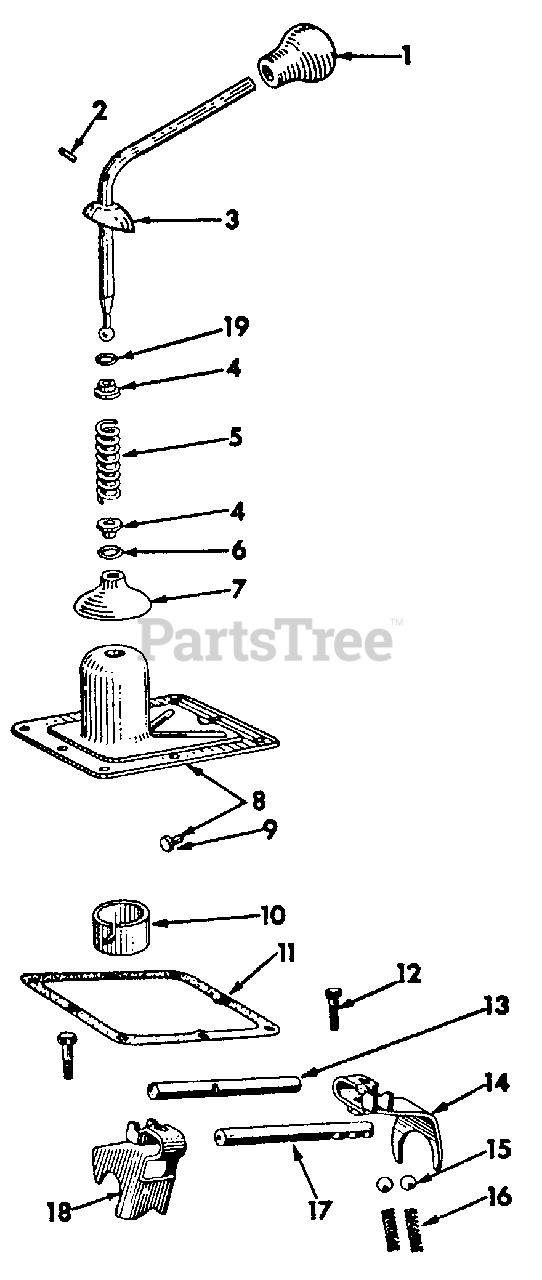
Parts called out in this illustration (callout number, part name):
1	Knob, Shift Handle
2	Pin, Gear Shift Swivel Spring Retainer
3	Lever Assy, Gear Shift
4	Retainer, Gear Shift Swivel Spring
5	Spring, Gear Shift Lever
6	O-Ring, 1/2 X 5/8 X 1/16
7	Shield, Gear Shift Lever
8	Housing Assy, Gear Shift Lever
9	Pin, Gear Shift Lever Swivel Stop
10	Guide, Gear Shift Lever
11	Gasket, Gear Shift Lever Housing
12	Screw, Shifter Fork
13	Rod, Second & Third Gear Shifter
14	Package, Second & Third Shifter Fork Service
15	Ball, 3/8 Cr-Stl Grade 3
16	Spring, Gear Shifter Poppet
17	Rod, First & Reverse Gear Shifter
18	Package, First & Reverse Shifter Fork Service
19	O-Ring, 1/2 X 5/8 X 1/16
